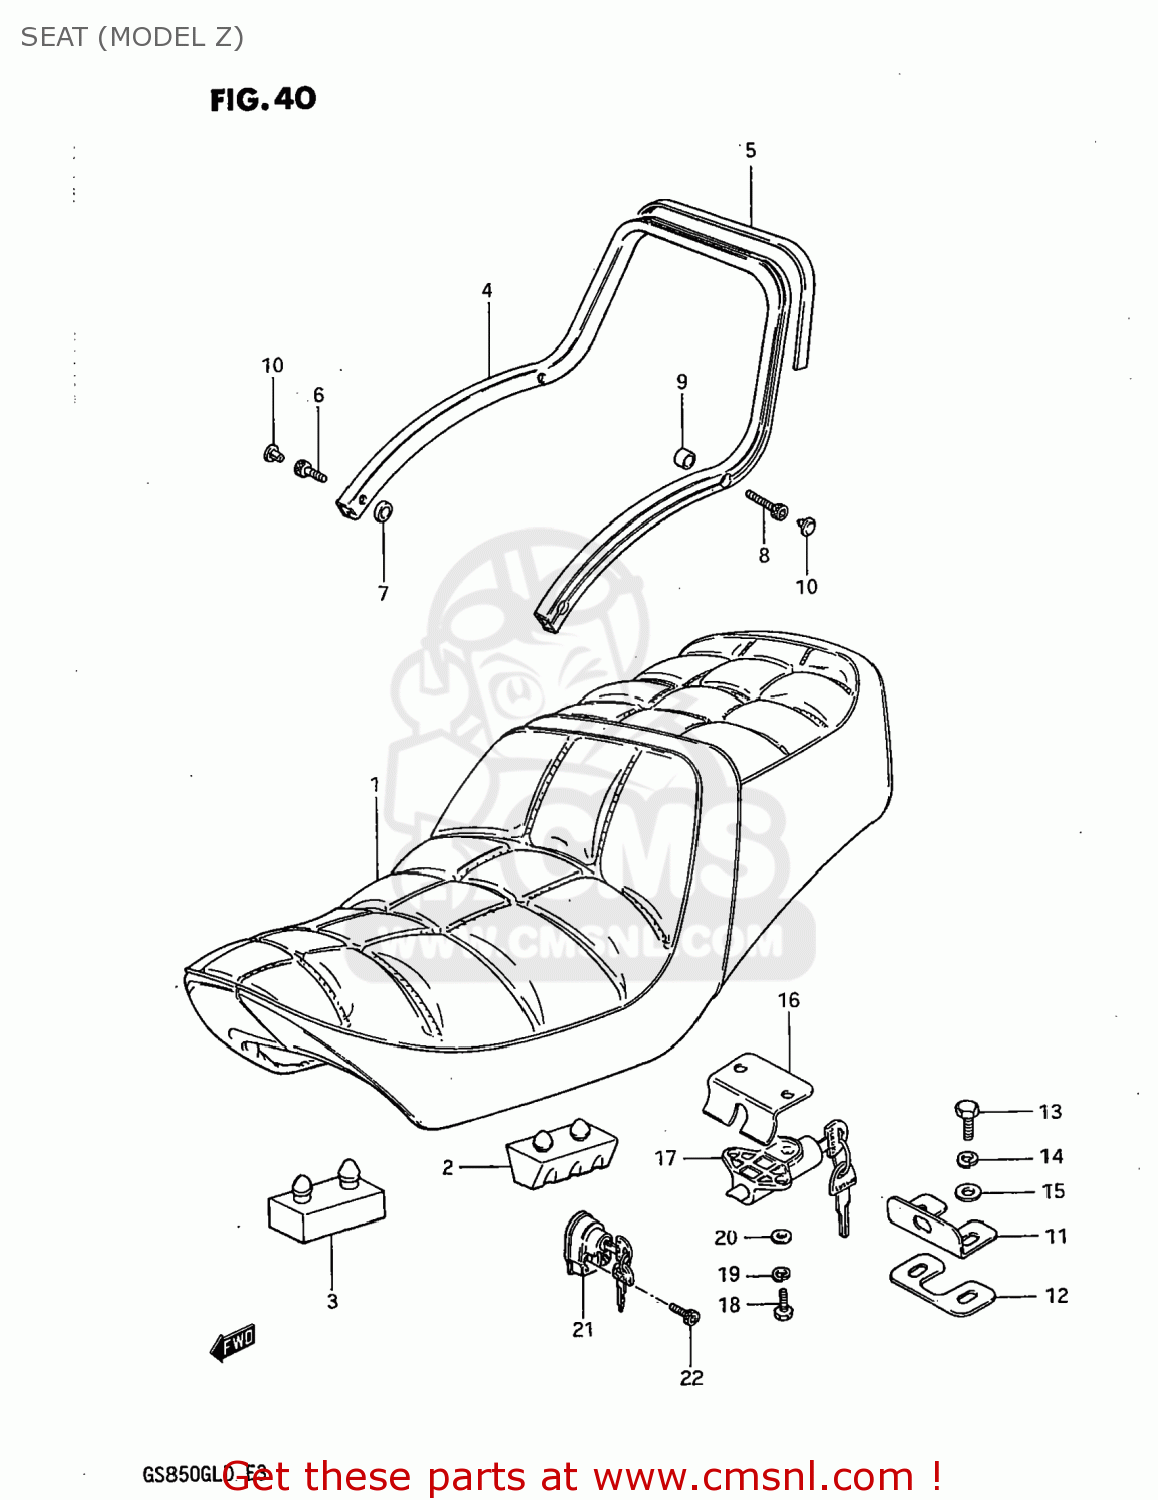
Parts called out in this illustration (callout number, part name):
1	SEAT ASSEMBLY
2	CUSHION,SUPPORT(50X25X32)
3	CUSHION
4	HANDLE,PILLION RIDER
5	RUBBER,PILLION RIDER HANDLE
6	BOLT
7	SPACER,REAR
8	BOLT
9	SPACER,REAR
10	CAP(OD:14.5)
11	STRIKER,SEAT LOCK
12	SHIM,SEAT LOCK STRIKER
13	BOLT, UPPER
14	LOCK WASHER
15	WASHER
16	PLATE,SEAT LOCK
17	LOCK ASSEMBLY,SEAT
18	BOLT
19	LOCK WASHER
20	WASHER 6MM
21	LOCK ASSY,HELMET
22	BOLT 5X25
